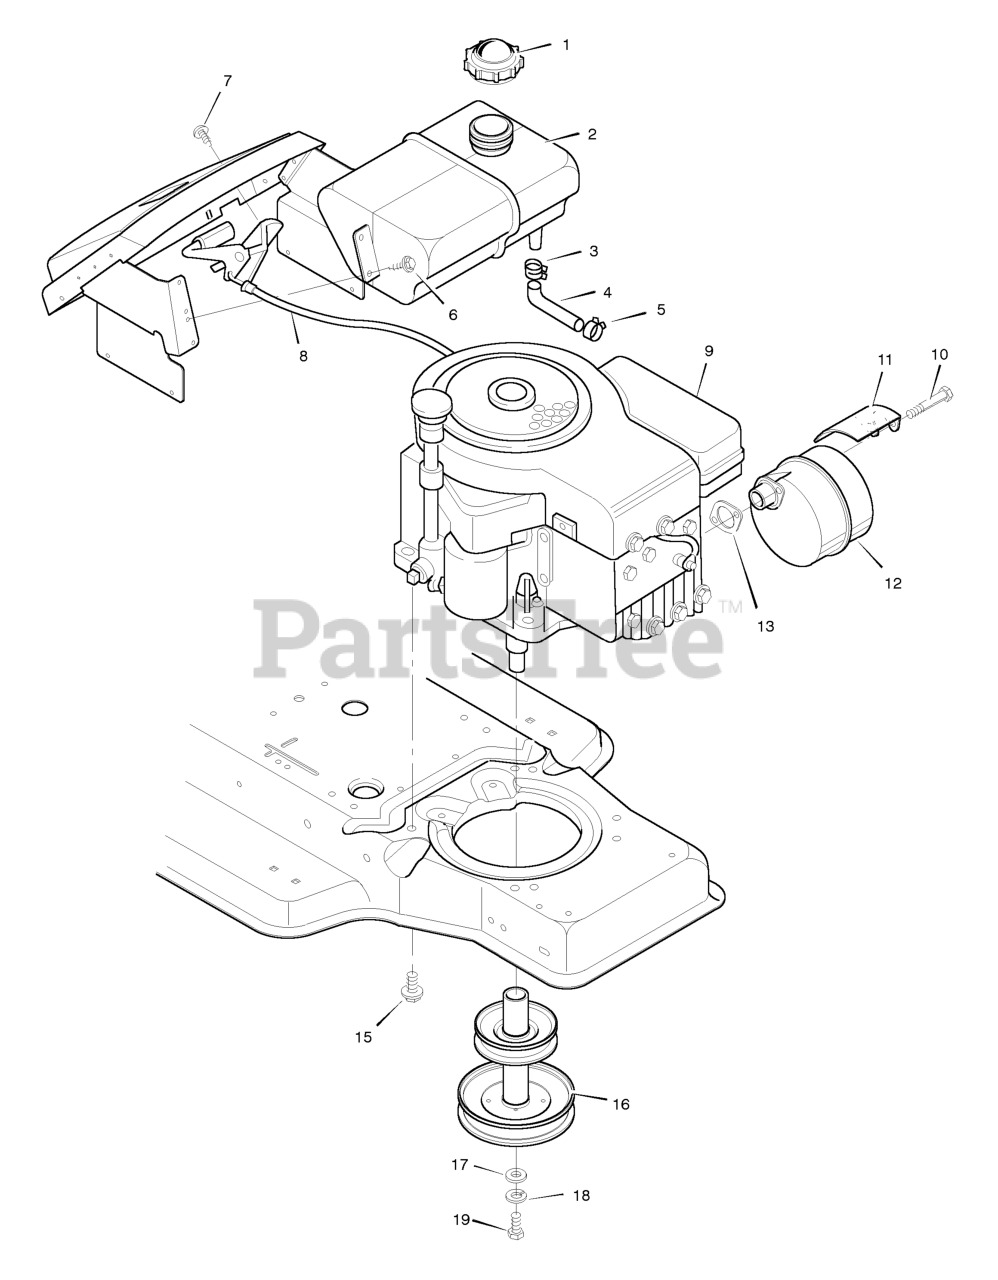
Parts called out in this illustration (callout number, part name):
1	Fuel Cap
2	Fuel Tank
3	Hose Clamp
4	Fuel Line
5	Hose Clamp
8	Throttle Control
9	Engine *
11	Shield, Heat
12	Muffler
13	GASKET, Exhaust
15	Bolt, Engine Mount
16	Pulley, Stack
18	Lockwasher
19	Bolt, Hex
